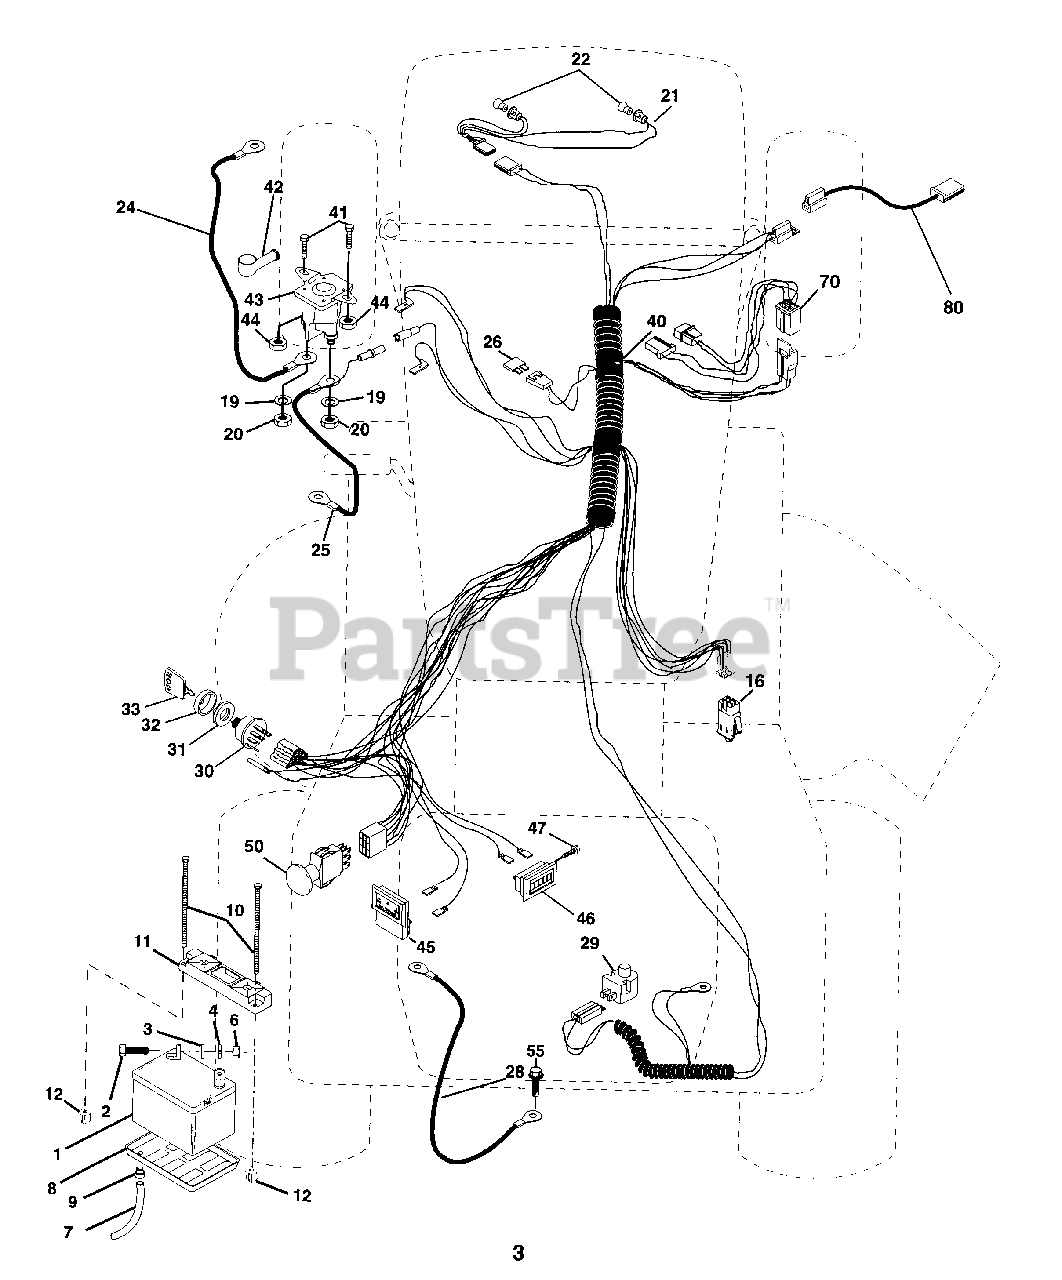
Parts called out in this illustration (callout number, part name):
1	Battery 12 Volt 30 AMP Wet
2	Bolt Hex Hd 1/4-20unc X 3/4
3	Washer 9/32 X 5/8 X 16 Ga.
4	Washer Lock Hvy Helical 1/4
6	Nut Fin Hex 1/4-20 Unc
7	Tube Plastic 46" Front
8	Tray, Battery 7.80 x 5.25 Blk
9	Clamp Hose Olive
10	Bolt BTR FRT 1/4-20 x 7.5 zinc
11	Holddown Battery, Front mount
12	Nut, Push Nylon 1/4 battery FRT
16	Switch Interlock Push-In
19	Washer Lock 1/4
20	Nut Jam Hex 1/4-20 Unc
21	Harness Asm Light W/4152j
22	Bulb Light #1156
24	Cable Starter 6 Ga 11" Red
25	Cable Battery 6 Ga 22" w/16W
26	Fuse 30 AMP Auto Green
28	Cable Ground 6 Ga 21" black
29	Switch Plunger Nc Gray
30	Switch Ign 4 pos w/lights
31	Nut ignition
32	Cover Sw Ignition
33	Key Ign Molded
40	Harness Ign. Elec. HM P/L
41	Bolt Blk Fin Hex 1/4 - 20 x 1/2
42	Cover Terminal Red
43	Solenoid
44	Nut Keps Hex 1/4-20 Unc
45	Ammeter, retangular 6 amp
46	Meter, Hour
47	Screw 10-24 x 1/2 Black
50	Switch PTO 3 PTO Black
55	Screw THDROL 5/16-18 x 1/2 TYT
70	Harness, Eng.
80	Harness, Clutch EVX
